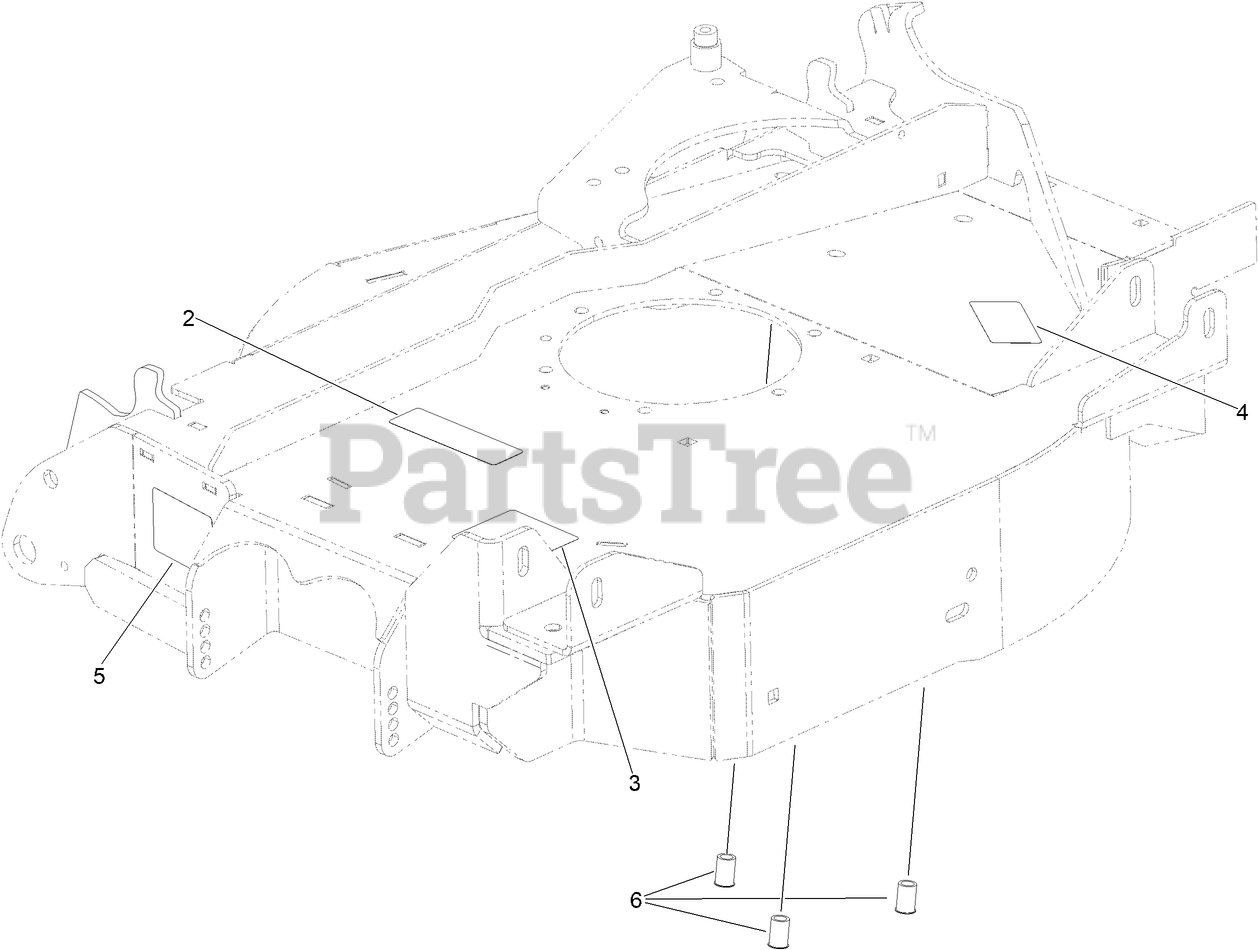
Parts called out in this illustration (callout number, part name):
2	DECAL-COVER, MISSING
3	DECAL-DANGER, THROWN OBJECT
4	DECAL-BOLT TORQUE
5	DECAL-WARNING, PINCH POINT
6	NUT-CLINCH
